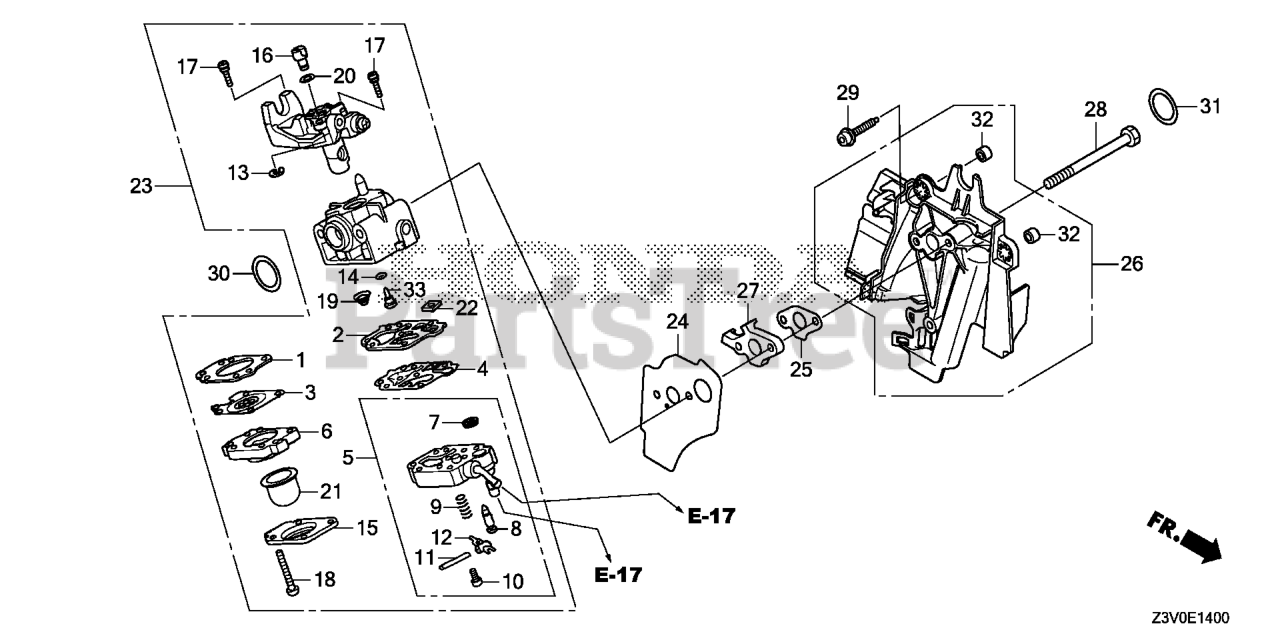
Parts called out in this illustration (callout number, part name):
1	GASKET, METERING DIAPHRAGM
2	GASKET, PUMP (CARBURETOR NO.)
3	DIAPHRAGM ASSY., METERING
4	DIAPHRAGM, PUMP
5	BODY ASSY., PUMP
6	BODY ASSY., AIR PURGE
7	SCREEN, INLET (CARBURETOR NO.)
8	VALVE, INLET NEEDLE
9	SPRING, METERING LEVER
10	SCREW, METERING LEVER PIN
11	PIN, METERING LEVER
12	LEVER, METERING
13	RING, RETAINING
15	COVER, PRIMER PUMP
17	SCREW, THROTTLE COLLAR
18	SCREW, PUMP COVER
19	SPRING, PUMP
21	PUMP, PRIMER
22	FILTER, FUEL INLET (CARBURETOR NO.)
23	CARBURETOR ASSY.
24	GASKET, CARBURETOR
25	GASKET, SHROUD
27	SPACER, SHROUD
28	BOLT (5X58)
29	BOLT, SOCKET (5X16)
30	O-RING (14.8X2.4)
31	O-RING (14.8X2.4)
32	COLLAR A, HEAD COVER
33	JET (#42)
33	JET (#43)
